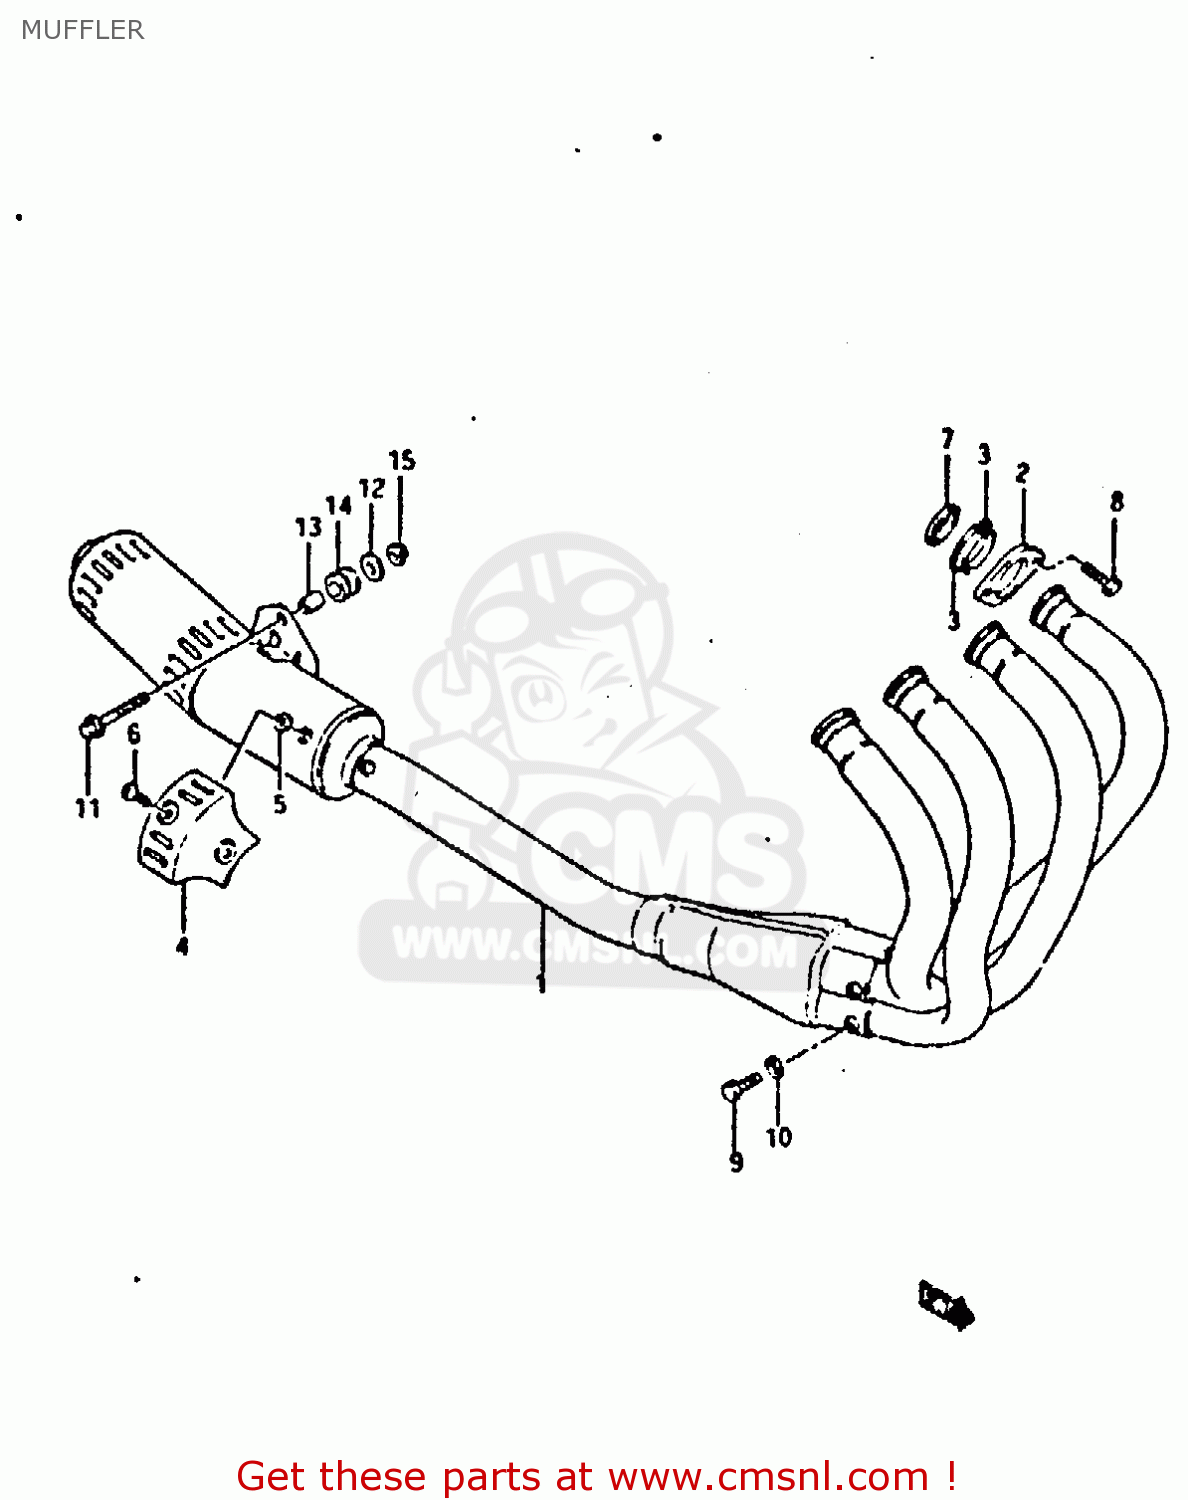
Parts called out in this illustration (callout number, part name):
1	UITLAAT SET
2	CLAMP,EXHAUST PIPE
3	PLATE,EXHAUST PIPE
4	COVER,2ND MUFF
5	GASKET (NAS)
6	SCREW
7	GASKET,EXHAUST PIPE
8	BOLT 8X23
9	BOLT
10	WASHER, LOWER
11	BOLT
12	WASHER
13	SPACER (8.6X12X17.5)
14	CUSHION
15	NUT 8MM
